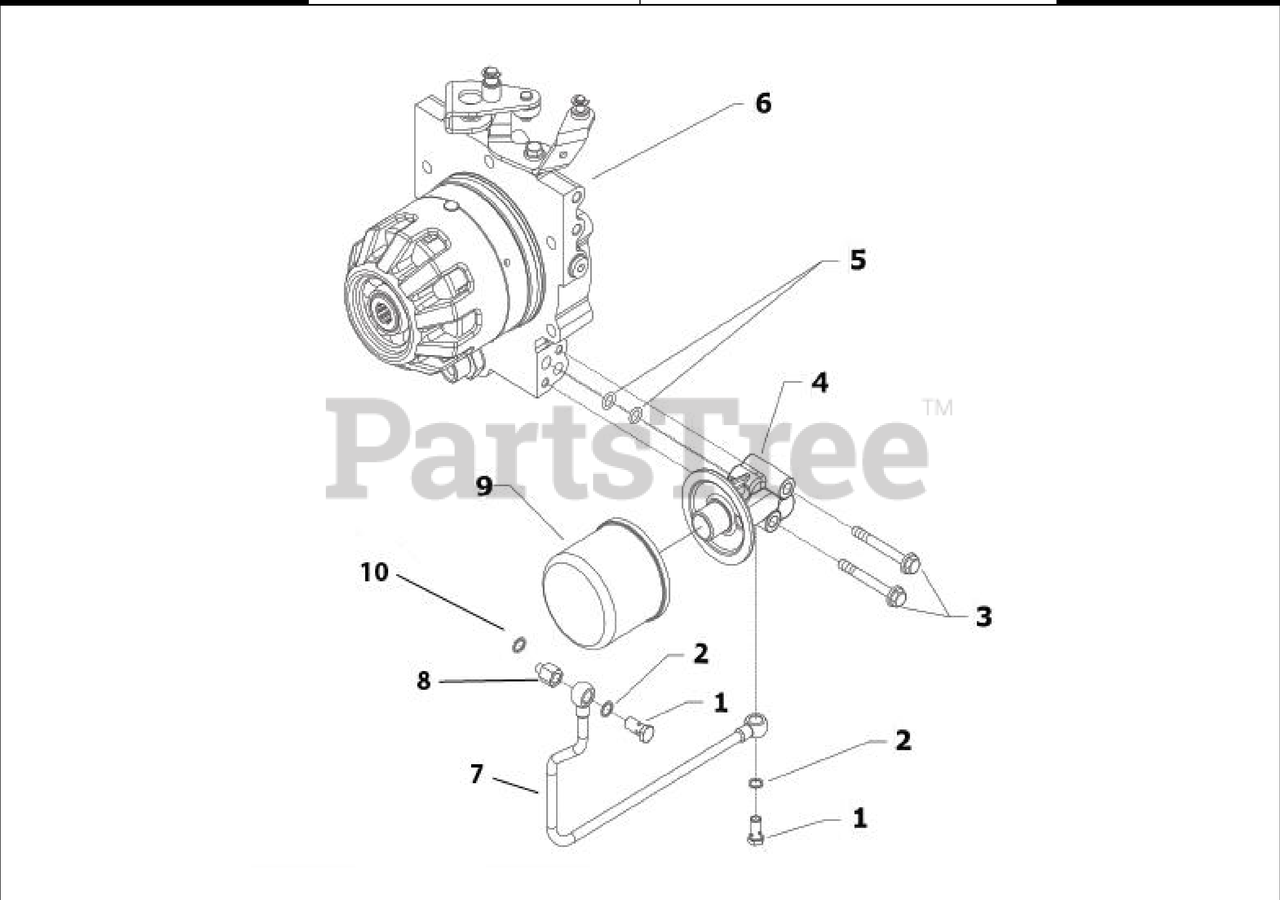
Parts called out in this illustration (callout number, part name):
1	PIPE FITTING BSPP
2	COPPER WASHER 16,7x22/1,5
3	SCREW TE C/F M6X50 DIN 6921 8G
4	CONNECTION
5	O-RING 108 (8.73X1.78)
6	POWERSAFE CLUTCH GX390 (3/8X24)
7	SUCTION PIPE
8	REDUCTION
9	FILTER
10	O-RING 3043 (10.78X2.62)
